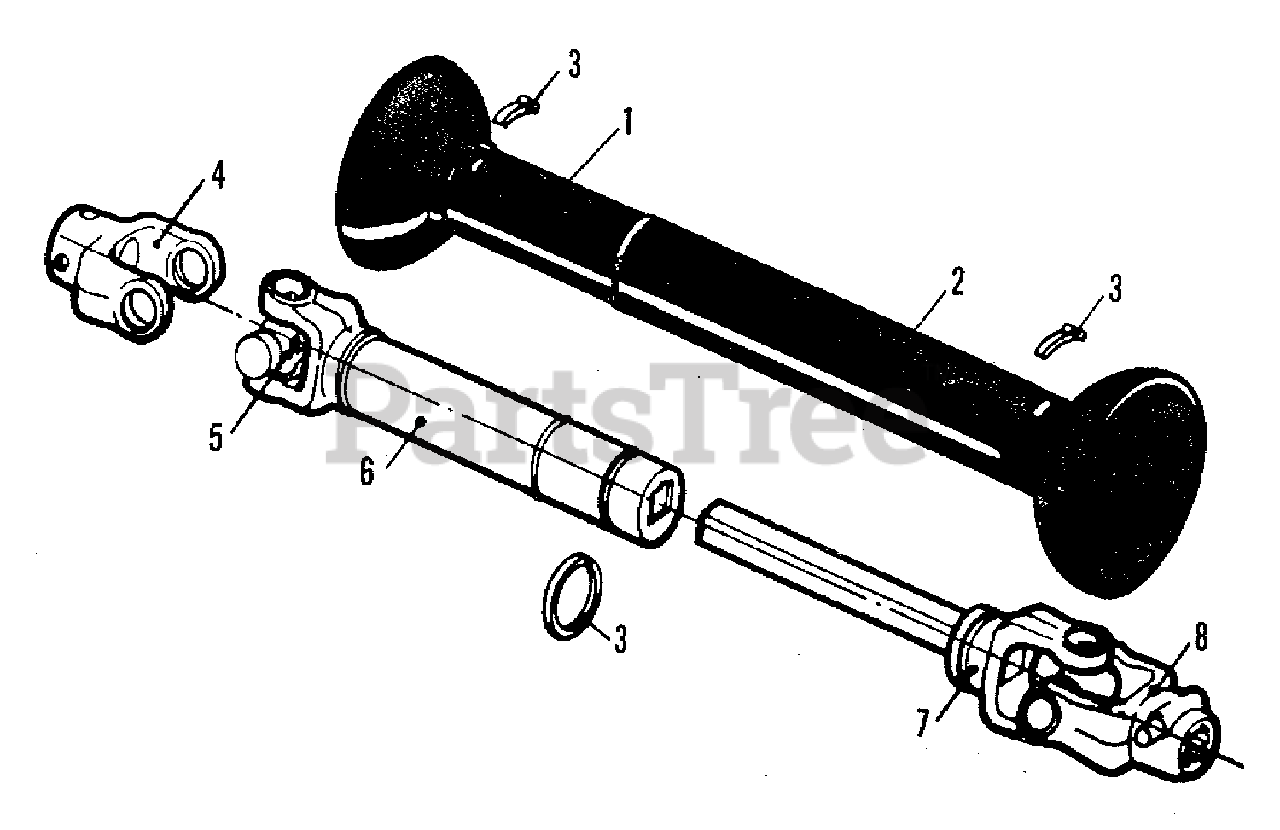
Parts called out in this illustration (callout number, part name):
1	SHIELD, Inner, Rear
2	SHIELD, Outer, Rear
3	BEARING KIT, Shield
4	YOKE, End, 1-1/4" Bore, 5/16" Cross Hole
5	CROSS KIT, U-Joint
6	SLEEVE ASSEMBLY, P.T.O.
7	SHAFT ASSEMBLY, P.T.O.
8	YOKE, Quick Disconnect, 1-3/8" x 68"
